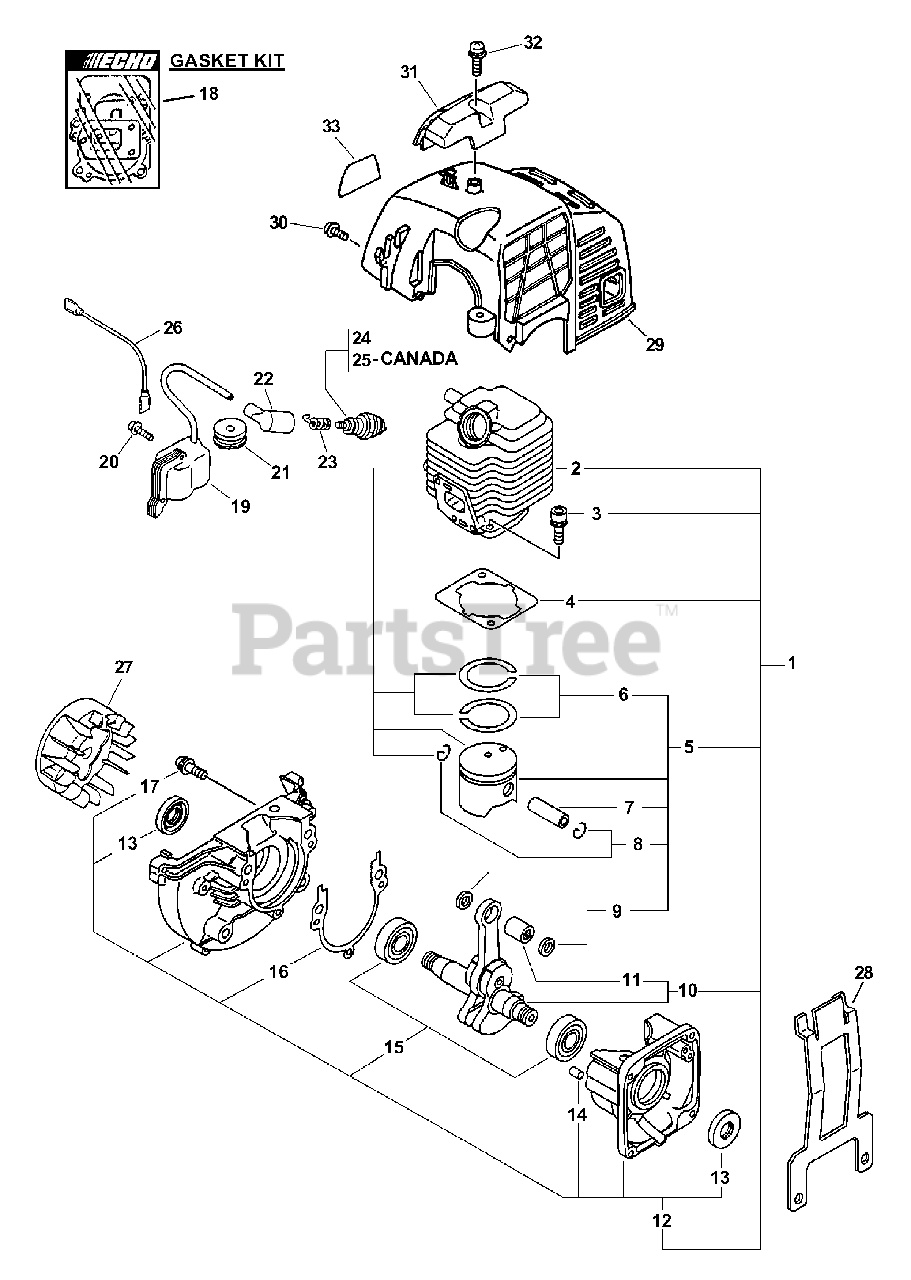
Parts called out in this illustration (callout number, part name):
1	SHORT BLOCK ES-2400
2	CYLINDER/PISTON KIT
3	BOLT 5×22
4	GASKET, CYLINDER
5	PISTON KIT
6	RING, PISTON
7	PIN, PISTON 8
8	RING, SNAP
9	WASHER, THRUST
10	CRANKSHAFT ASSY
11	BEARING, NEEDLE 8
12	CRANKCASE KIT
13	SEAL, OIL 12
14	PIN, LOCATING 4
15	BEARING, BALL - 6201 C3
16	GASKET, CRANKCASE
17	BOLT 5×28
18	GASKET KIT
19	COIL, IGNITION
20	SCREW 4×22
22	CAP, SPARK PLUG
23	TERMINAL, SPARK PLUG
24	SPARK PLUG - BPM-7Y
25	SPARK PLUG - BPMR7A
26	LEAD
28	GUARD, ENGINE
29	COVER, ENGINE - ORANGE
30	SCREW 4×12
31	GUARD, TOP - BLACK
32	SCREW 5×16
33	LABEL, PPT-2400
